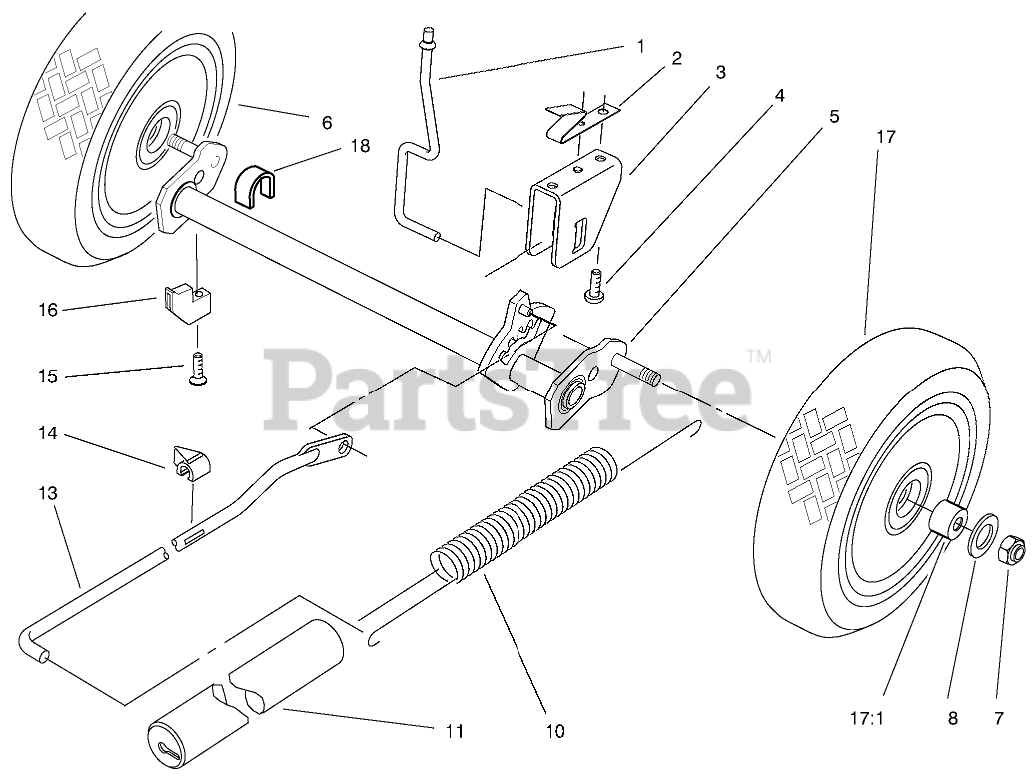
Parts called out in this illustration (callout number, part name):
1	ROD-TRIGGER
2	SPRING-RETURN, TRIGGER
3	SADDLE-HEIGHT OF CUT
4	SCREW-RH
5	AXLE-REAR
6	Wheel-Rear (Incl. Ref. #19)
7	NUT-HH
8	WASHER-WHEEL
10	SPRING-COUNTERBALANCE
11	COVER-SPRING
13	ROD-LINK
14	INDICATOR-HEIGHT OF CUT
15	SCREW-RETAINER
16	RETAINER-AXLE
17	Wheel-Rear (Incl. Ref. #19)
17:1	BUSHING
18	CAP-AXLE, REAR
